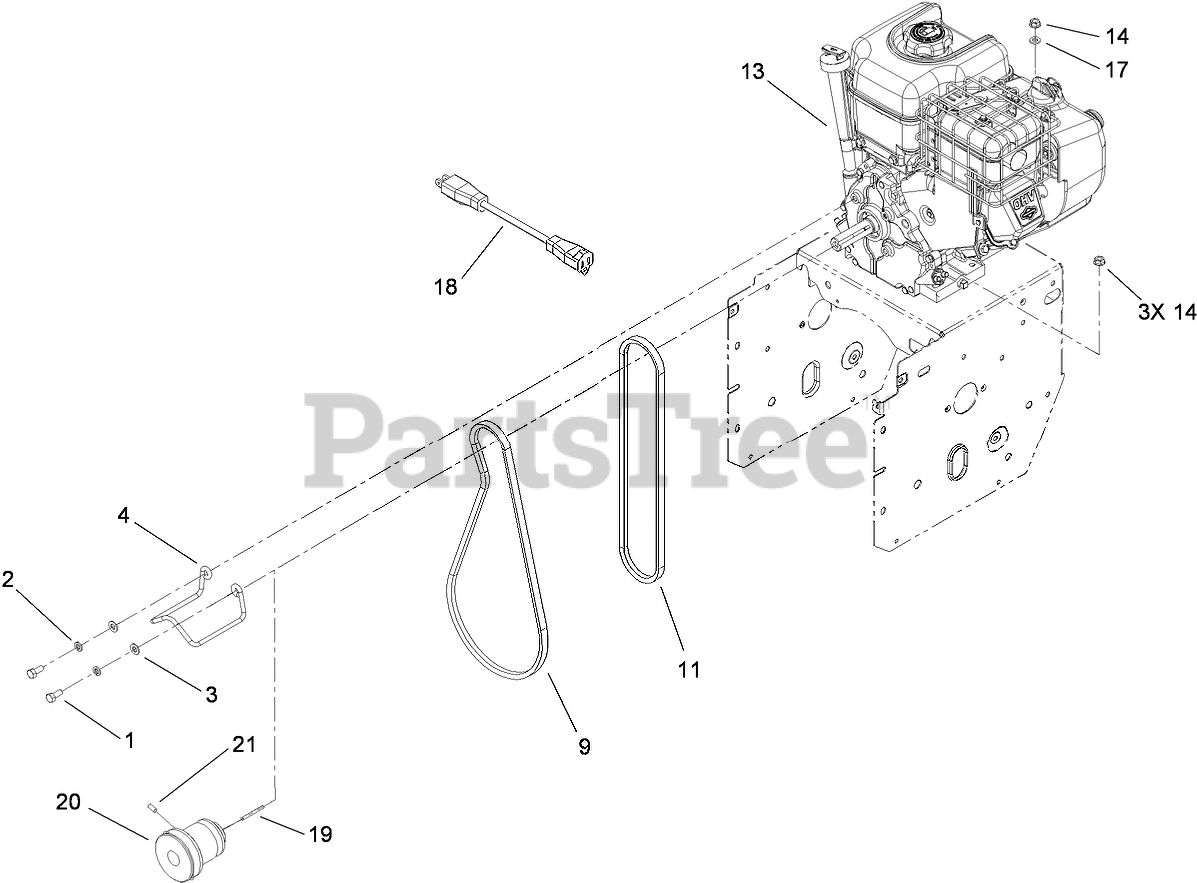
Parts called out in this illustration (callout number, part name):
1	SCREW-HH
2	WASHER-LOCK
3	WASHER-PLAIN
4	GUIDE-BELT
9	BELT-V
11	V BELT-TRACTION
14	NUT-HF
17	WASHER-FLAT
18	CORD-EXTENSION
19	KEY-SQUARE
20	PULLEY-ENGINE
21	SCREW-SET, HSH
